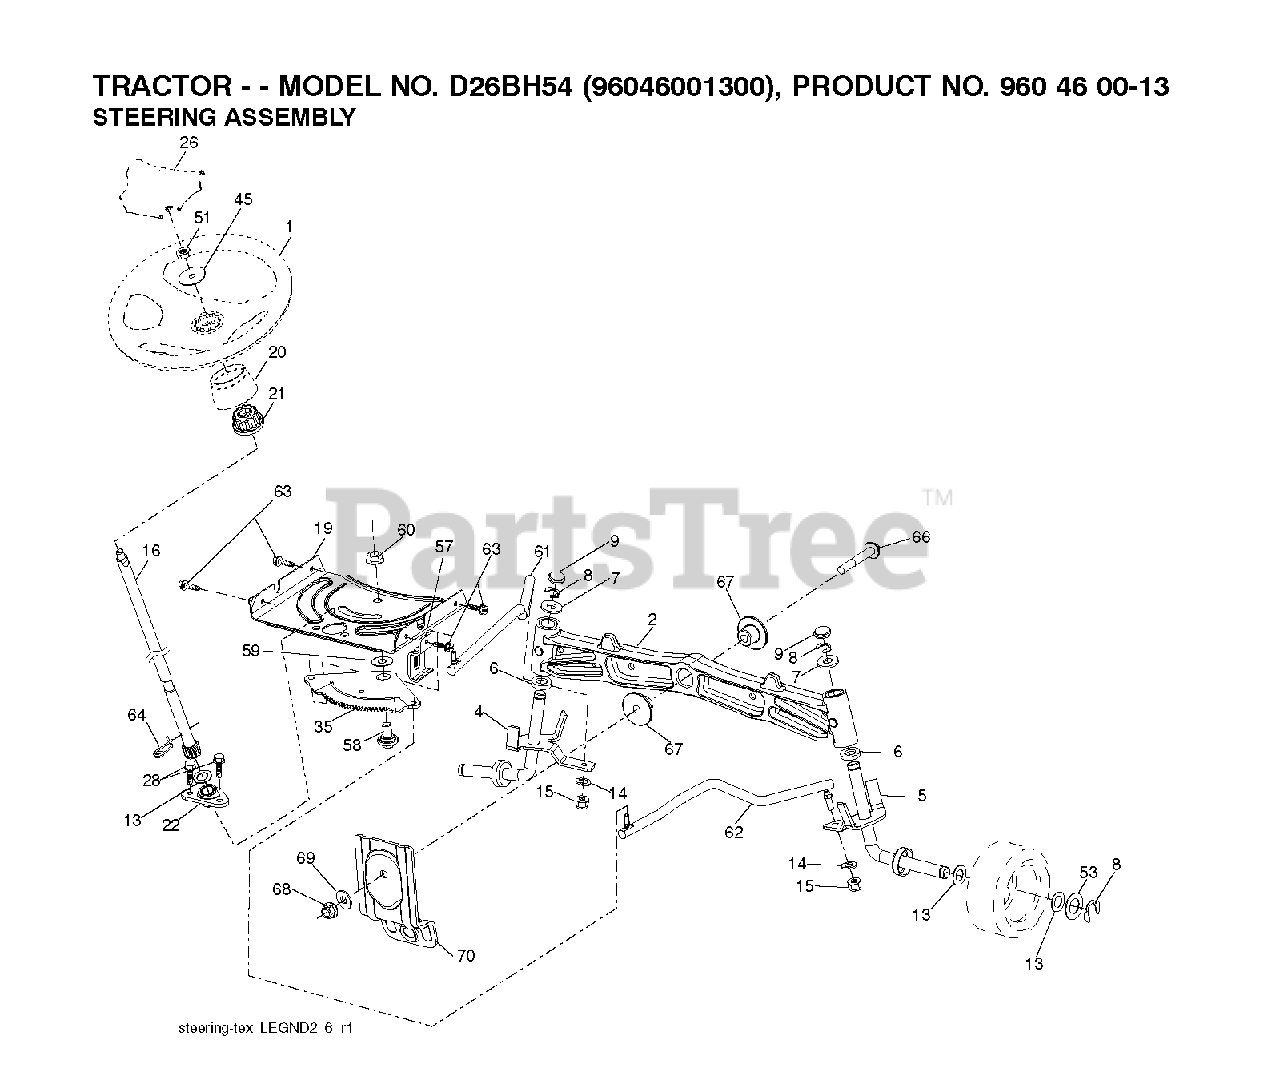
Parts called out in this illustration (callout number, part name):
1	WHEEL.STEERING.STDSRR.BLK/OV
2	AXLE.CAST.IRON
4	SPINDLE.WELDED.LH.16"TEX
5	SPINDLE.WELDED.RH.16"TEX
8	RING CLIP
9	CAP.SPINDLE.BLACK
14	WASHER, LOCK 3/8
15	NUT CROWNLOCK 3/8-24
16	SHAFT, STEERING
19	PLATE.STEER.DDL.NLT/NG
20	BOOT.STEERING.
21	ADAPTER, WHEEL STNG..
22	STEERING.SUPT.LOWER.
26	INSERT, WHEEL STEERING
28	SCREW, 3/8-16X3/4
35	GEAR.SECTOR.PLATE.DDL.
45	WASHER.11/32
51	NUT.HEX.1/2-20
53	WASHER.HARDENED
57	BRKT.UPSTOP.GT/LT.TEX
58	BOLT.SHOULDER.SECTOR.P
59	WASHER.THURST.SECTOR.S
60	NUT FLANGE LOCK 5/8-11
61	DRAGLINK.LH.BALLSTUD.D
62	DRAGLINK.RH.BALLSTUD.D
63	SCREW
64	RETAINER.CLIP.SPRING.S
66	BOLT HEX FGHD 7/16-14 X 3 SERR
67	BUSHING.PM.FRONT AXLE
68	NUT.LOCK.FLANGE.7/16
69	WASHER.1.5X.505X.118
70	BRKT.DECK.SUSPENSION.F
